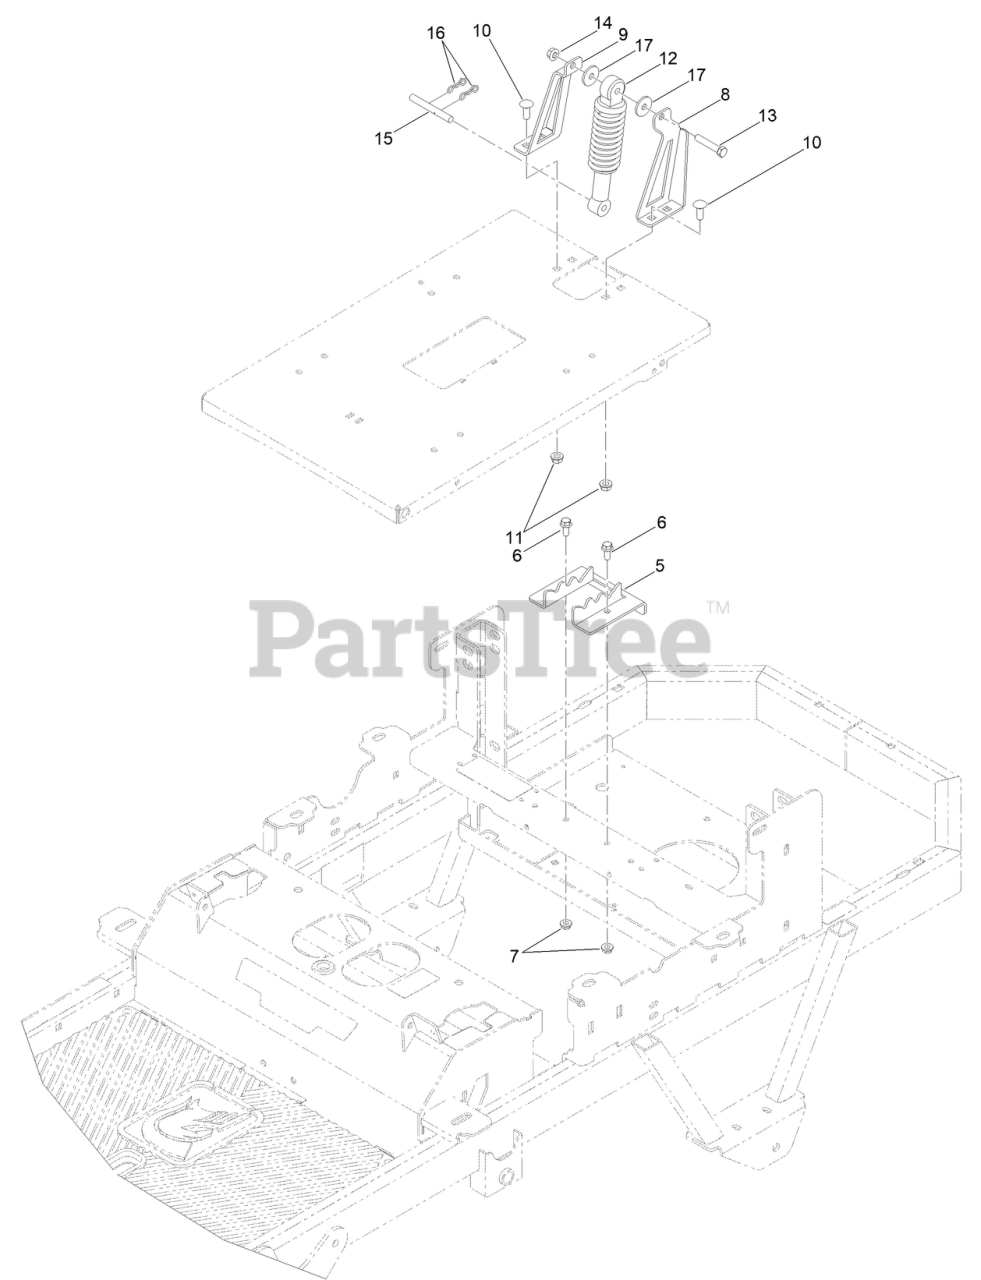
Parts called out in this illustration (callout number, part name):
5	RZ MWR SEAT SHOCK LWR MOUNT BRKT PAINT
6	SCREW-HHF
7	NUT-HF
8	RZ MWR SEAT SHOCK UPP MNT BRKT LT PAINT
9	RZ MWR SEAT SHOCK UPP MNT BRKT RT PAINT
10	SCREW-CARR
11	NUT-HHF, WHIZ
12	2020 RZ PRO SEAT / FT FORK SHOCK
13	3/8-16 X 2 HEX BOLT GR 5 ZINC YELLOW
15	RZ MWR SEAT SHOCK 10MM PIN
16	.073 DIA X 1-7/16IN HAIRPIN COTTER ZINC
17	FLT WASHER 1.25ODX.38IDX.125 THK PLA
